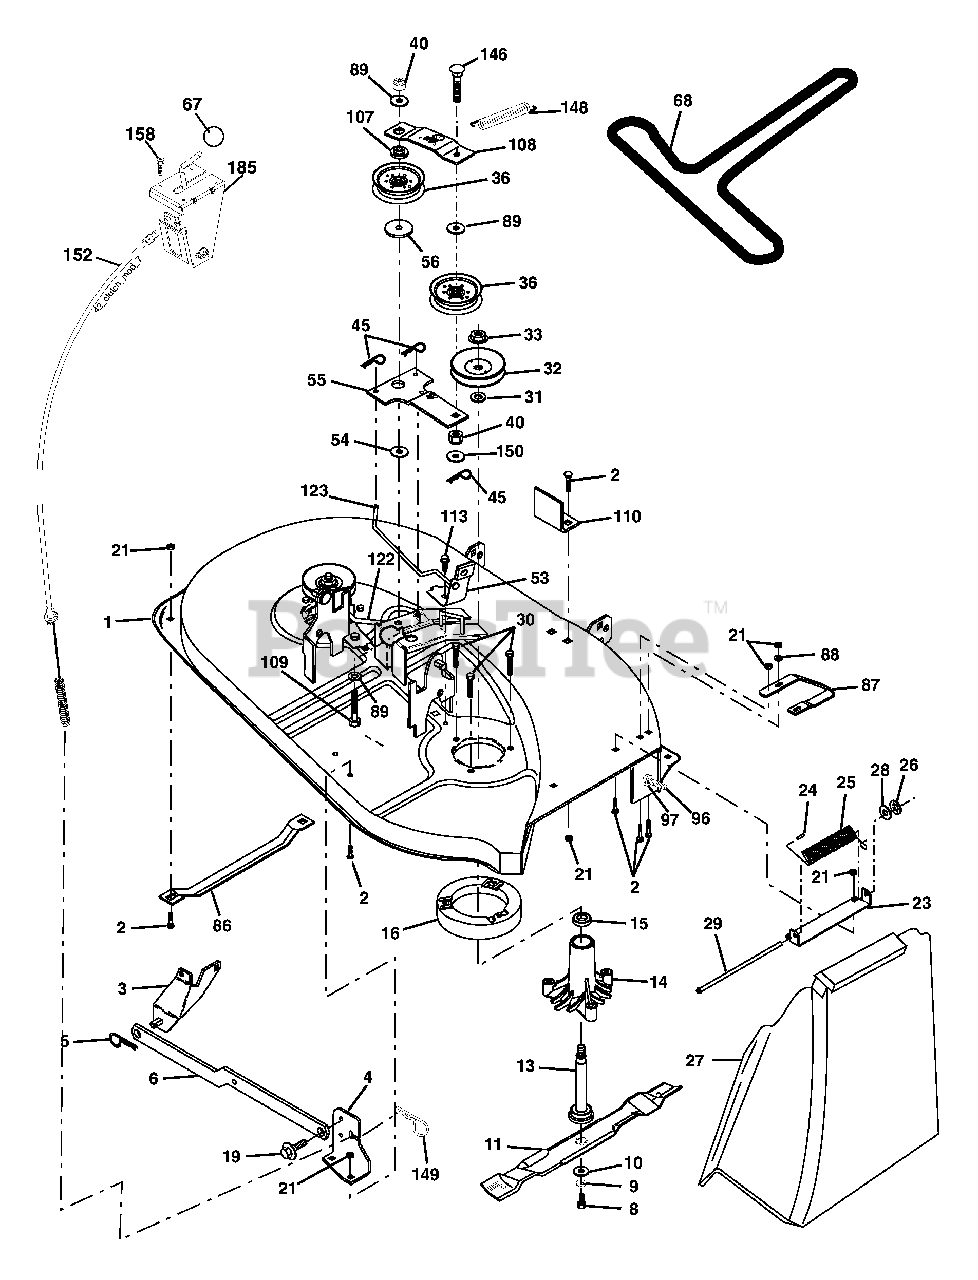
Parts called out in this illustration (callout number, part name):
1	Mower Housing Assembly
2	Bolt Carriage 5/16-18 x 3/4
3	Bracket Asm Fr. Sway Bar
4	Bracket Deck Sway Bar 38"/42"
5	Retainer Spring
6	Bar Sway Deck
8	Bolt 3/8-24 x 1.25 Gr. 8
9	Washer, Lock 3/8
10	Washer, Hardened
11	Blade, 38" Mulching Std
11	Blade, 38" Mulching Premium
11	Blade, 38" Hi-Lift
13	Shaft Assembly, Mandrel, Vented
14	Housing, Mandrel, Vented
15	Bearing, Ball, Mandrel
16	Stripper, Vented Mower Deck
19	Bolt, Shoulder
21	Nut
23	Bracket, Mower Deflector
24	Cap, Sleeve
25	Spring, Torsion, Deflector
26	Nut, Push
27	Shield, Deflector
28	Washer 11/32 x 5/8 x 16 Ga.
29	Rod, Hinge
30	Screw Thdrol. Washer Head
31	Washer, Spacer
32	Pulley, Mandrel
33	Nut, Toplock
36	Pulley, Idler, Flat
40	Nut, Crownlock 3/8-16 unc
45	Retainer
53	Brake Assembly
54	Washer, Hardened
55	Idler Arm Assembly
56	Spacer, Retainer
67	Knob
68	V-Belt, 42" Mower
86	Runner, LH
87	Runner, RH
88	Washer 11/32 x 3/4 x 16 Ga.
89	Washer 13/32 x 13/16 x 11 Ga.
96	Bolt 3/8-16 x 1-1/4 Mulcher
97	Nut Centerlock 3/8-16 unc
107	Spacer Retainer
108	Stiffener, Idler Arm
109	Bolt, Hex Hd 3/8-16 x 2-1/2
110	Upstop Deck Front 38"
113	Screw 5/16-1/ x 3/4
122	Rod, Brake LH
123	Rod, Brake RH
146	Bolt Carriage Idler
148	Spring Return Idler
149	Retainer Spring Yellow
150	Washer 9/32 x 3/4 x 10 Ga.
152	Clutch Cable 38"/46"
158	Screw Hex Thd Cut 1/4-20 x 1/2
185	Head Asm Cable Clutch
